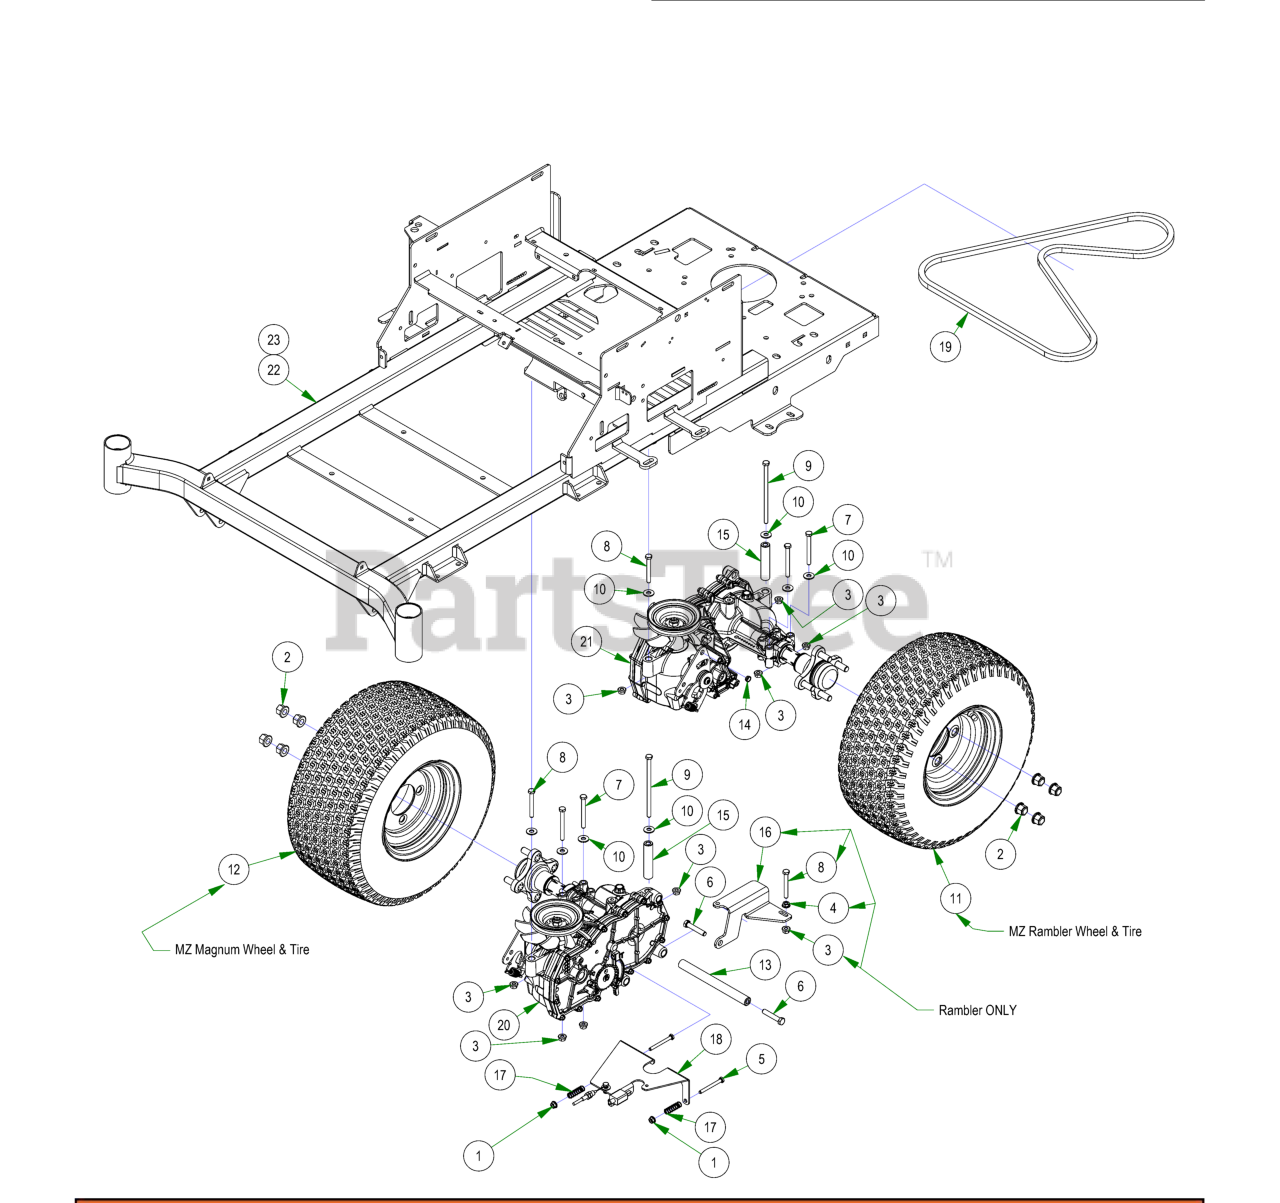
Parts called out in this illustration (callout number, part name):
1	1/4-20 NYL INSERT FLANGE LOCKNUT ZINC
2	Acorn Lug Nut
3	5/16-18 NYLON INSERT FLANGE LOCKNUT ZINC
4	5/16-18 HEX SERRATED FLANGE NUT HARD/ZINC
5	1/4-20 X 2-1/2 HEX CAP SCREW (GR.2) ZINC
6	3/8-16 X 2 HEX CAP SCREW (GR.5) ZINC
7	5/16-18 X 3 HEX CAP SCREW (GR.5) ZINC
8	5/16-18 X 2-1/2 HEX CAP SCREW (GR.5) ZINC
9	5/16-18 X 6 HEX CAP SCREW (GR.5) ZINC
10	5/16 USS FLAT WASHER (7/8 OD) ZINC
11	18X8.50-8 w/8" Tire & Wheel (Black)
12	18x9.50-8 Tire and Wheel - Black Wheel
13	2017 Transaxle Spacer-MZ
14	Drive Arm Transaxle Spacer
15	2017 Transaxle Spacer
16	Ogura Clutch Belt Retainer
17	Brake Spring
18	MZ Brake Plate Assembly w/ Brake Cable
20	2017 EZT -Right -MZ Models
21	2017 EZT -Left -MZ Models
22	2024 MZ 42-48 Frame
23	2024 MZ-Avenger 54-60 Frame
